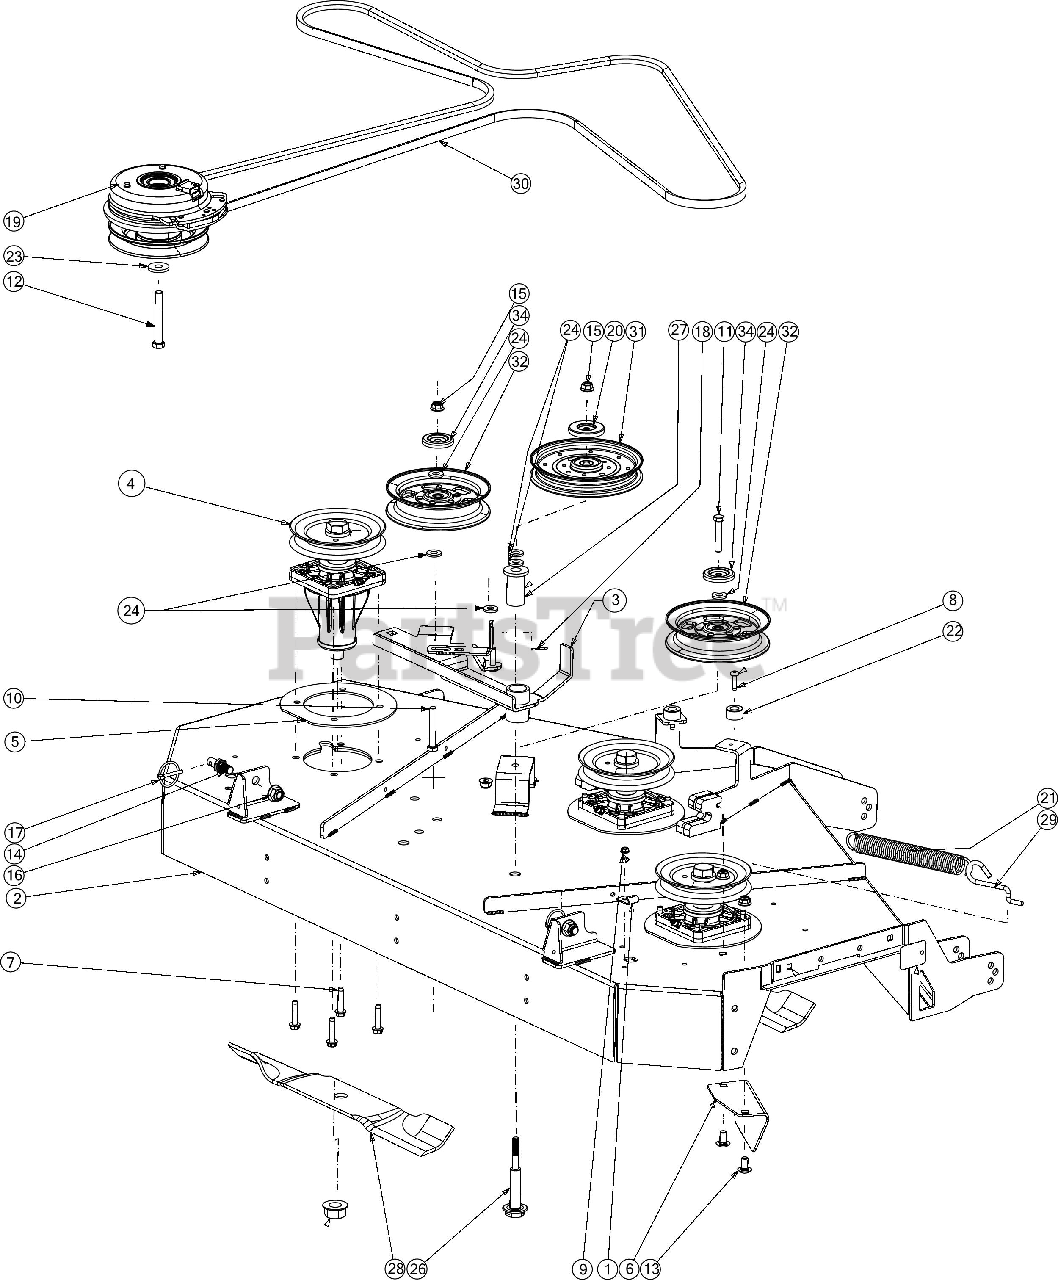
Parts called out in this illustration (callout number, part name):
1	HOOK RETAINING BRACKET
2	54" FAB DECK SHELL
3	54/60" DECK IDLER ASSEMBLY
4	BLADE SPINDLE ASSEMBLY (W/PULLEY)
5	SPINDLE REINFORCEMENT PLATE
6	DECK CHUTE BAFFLE
7	SCREW 5/16-18 X 1.50
8	SCREW 1/4-20 X 1.0
9	SCREW 1/4-20 X.500
10	HEX SCREW-3/8-16X2.5 GR5
11	SCREW 3/8-16 X 2.0 GR5
12	SCREW 7/16-20 x 3.25 GR5
13	CARRIAGE BOLT 3/8-16 X .75
14	DECK PIN
18	COTTER PIN 3/32
19	ELECTRIC PTO CLUTCH
20	PULLEY CAP
21	EXTENSION SPRING
23	FLAT WASHER .445 X 1.248 X .170
24	FLAT WASHER
26	SHOULDER BOLT
27	SHOULDER SPACER
28	19" BLADE (HI LIFT)
29	DECK SPRING HOOK
30	V-BELT B SEC X 154
31	IDLER PULLEY
32	IDLER PULLEY 5.0
34	IDLER PULLEY CAP
